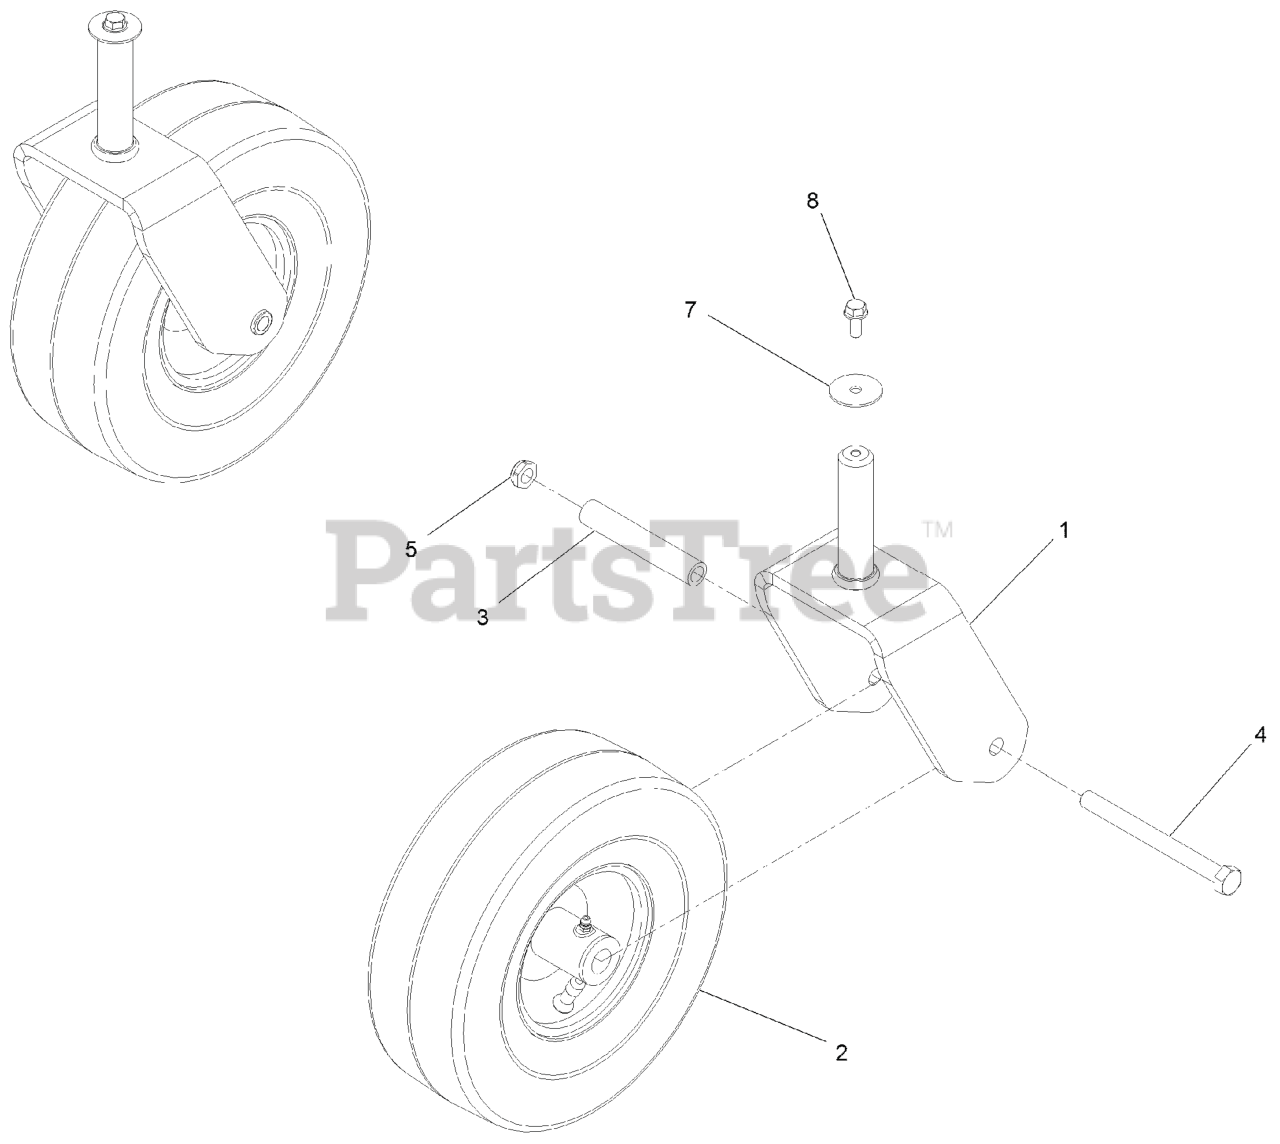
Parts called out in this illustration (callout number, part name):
1	FORK-CASTER
2	TIRE AND WHEEL ASM (C S T)
3	BUSHING-SPANNER
4	SCREW-HH
5	NUT-HEX
7	WASHER-FLAT
8	SCREW-HHF
